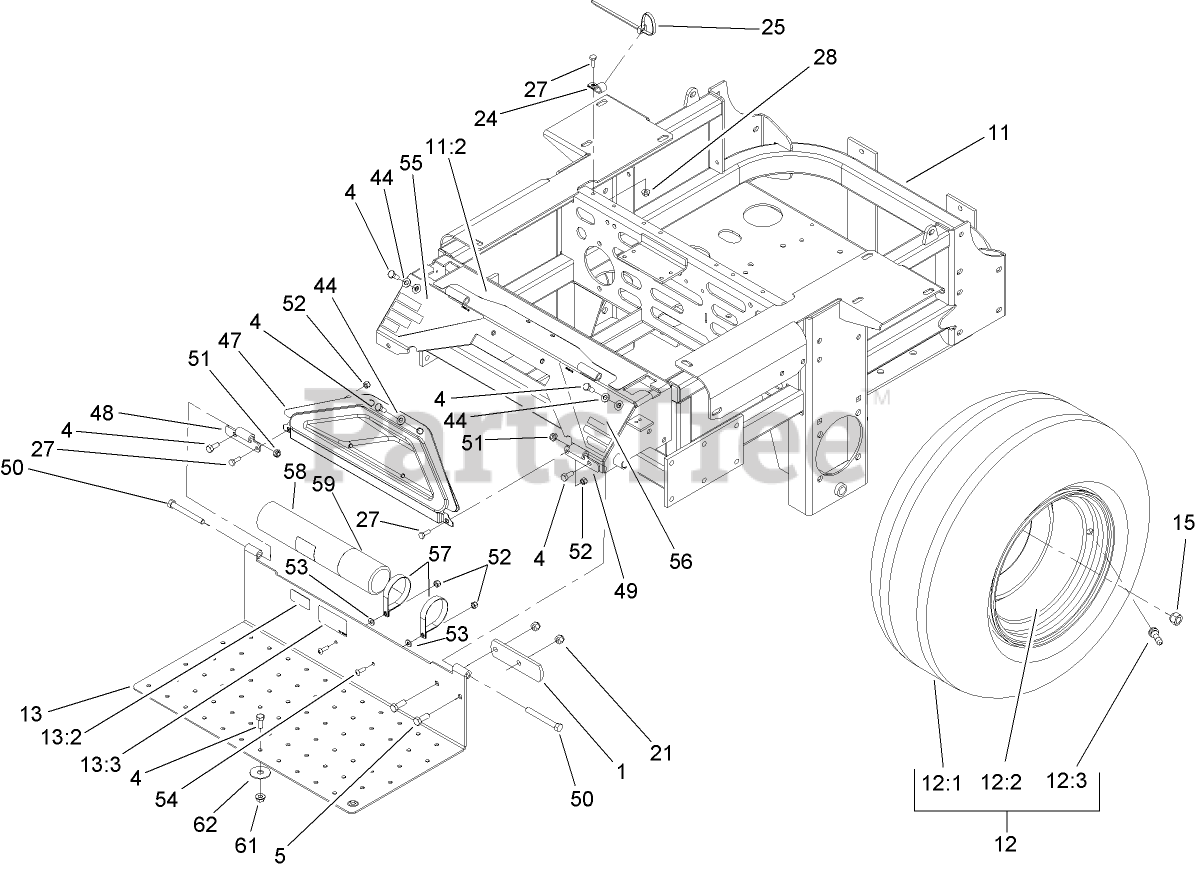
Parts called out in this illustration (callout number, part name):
1	STOP-BRAKE, PARK
4	SCREW-HH
5	SCREW-HH
11	MAIN FRAME ASM
11:2	DECAL-CONSOLE, TOP
12	WHEEL AND TIRE ASM
12:2	WHEEL RIM
12:3	STEM-VALVE
13	FLOORPAN
13:2	DECAL-PROTECTION, EAR
13:3	DECAL-LOCATION, MANUAL
15	NUT-LUG
21	NUT-LOCK, NI
24	CLIP-LOOM
25	TIE-PLASTIC
27	SCREW-HH
28	NUT-HF
44	WASHER-FLAT
47	Pocket
48	Hinge-Floorpan, LH
49	Hinge-Floorpan, RH
50	SCREW-HH
51	NUT-LOCK, NI
52	NUT-LOCK, NI
53	WASHER-FLAT
54	SCREW-PRH
55	DECAL-WARNING, RIGHT
56	DECAL-DANGER, LEFT
57	R-Clamp
58	TUBE-MANUAL
59	CAP-HOUSING
61	NUT-HF
62	WASHER
